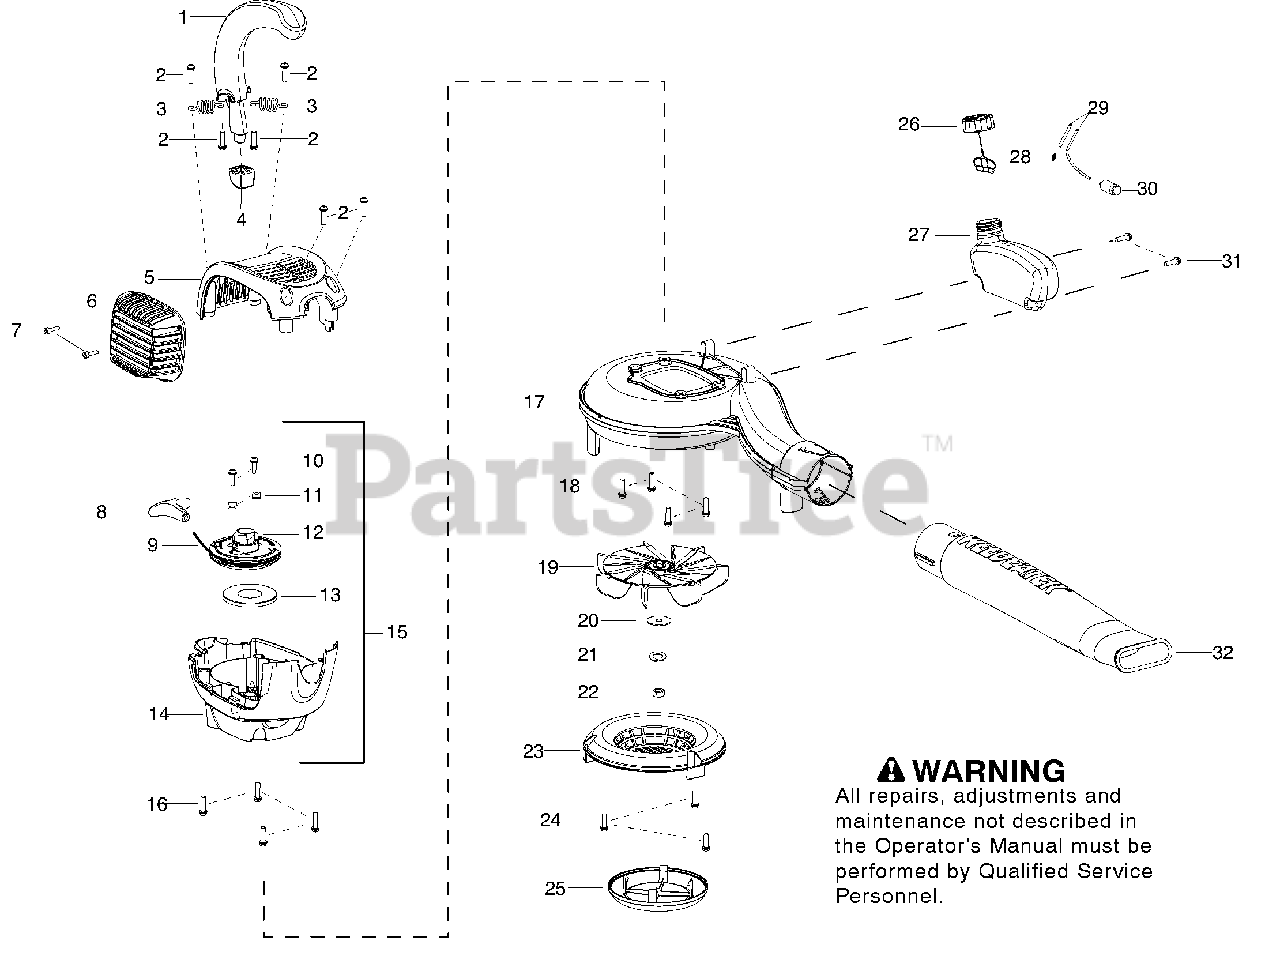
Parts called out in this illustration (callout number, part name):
1	Assy - Handle
3	Spring - Isolator
4	Isolator - Handle
5	Housing - Upper Engine
6	Assy - Muffler Guard
8	Handle - Starter
10	Screw - Retainer
12	Kit - Starter Pulley
13	Spring - Starter
14	Assy - Fan housing with bearing
15	Assy - Lower Engine Housing
16	Screw
17	Assy - Scroll Housing
19	Assy - Impeller
20	Washer - Impeller
21	Washer - Lock
23	Cover - Inlet
25	Deflector - Intake
26	Cap - Fuel (w/retainer)
27	Assy - Fuel Tank
28	Fitting - Fuel Line
29	Kit - Fuel Line
30	Assy - Fuel Pick-up
32	Tube - Blower
